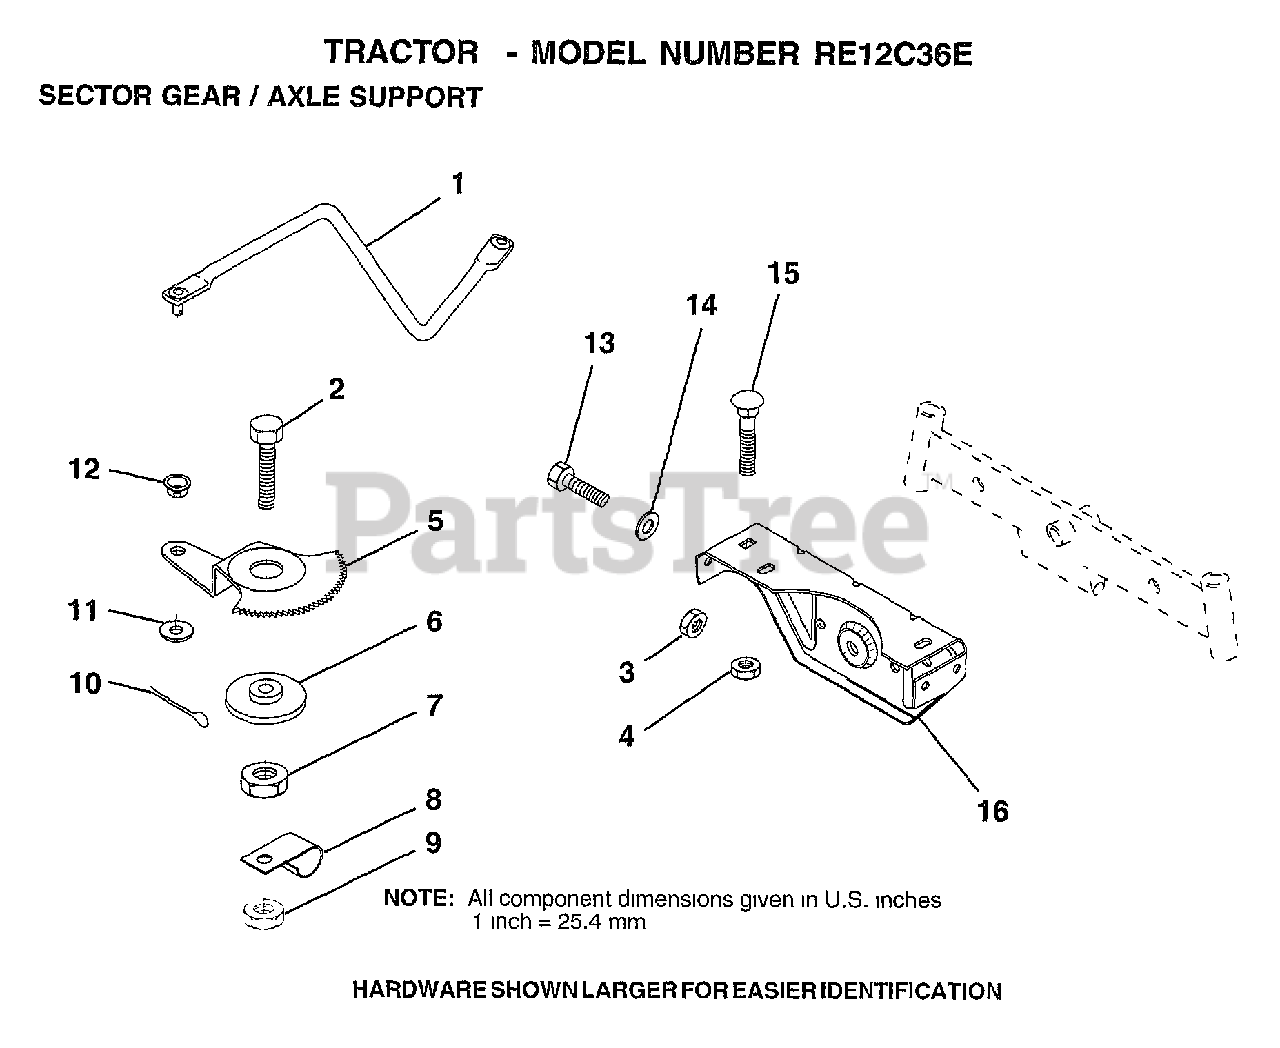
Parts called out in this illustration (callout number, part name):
1	DRAG LINK
2	"BOLT,HEX"
5	GEAR SECTOR
6	BUSHING
7	NUT
8	CLIP INSULATOR
9	NUT LTV
10	COTTER PIN
11	WASHER
12	BUSHING.DRAGLINK
13	BOLT
14	WASHER
15	BOLT
16	SUPT AXLE FRONT
